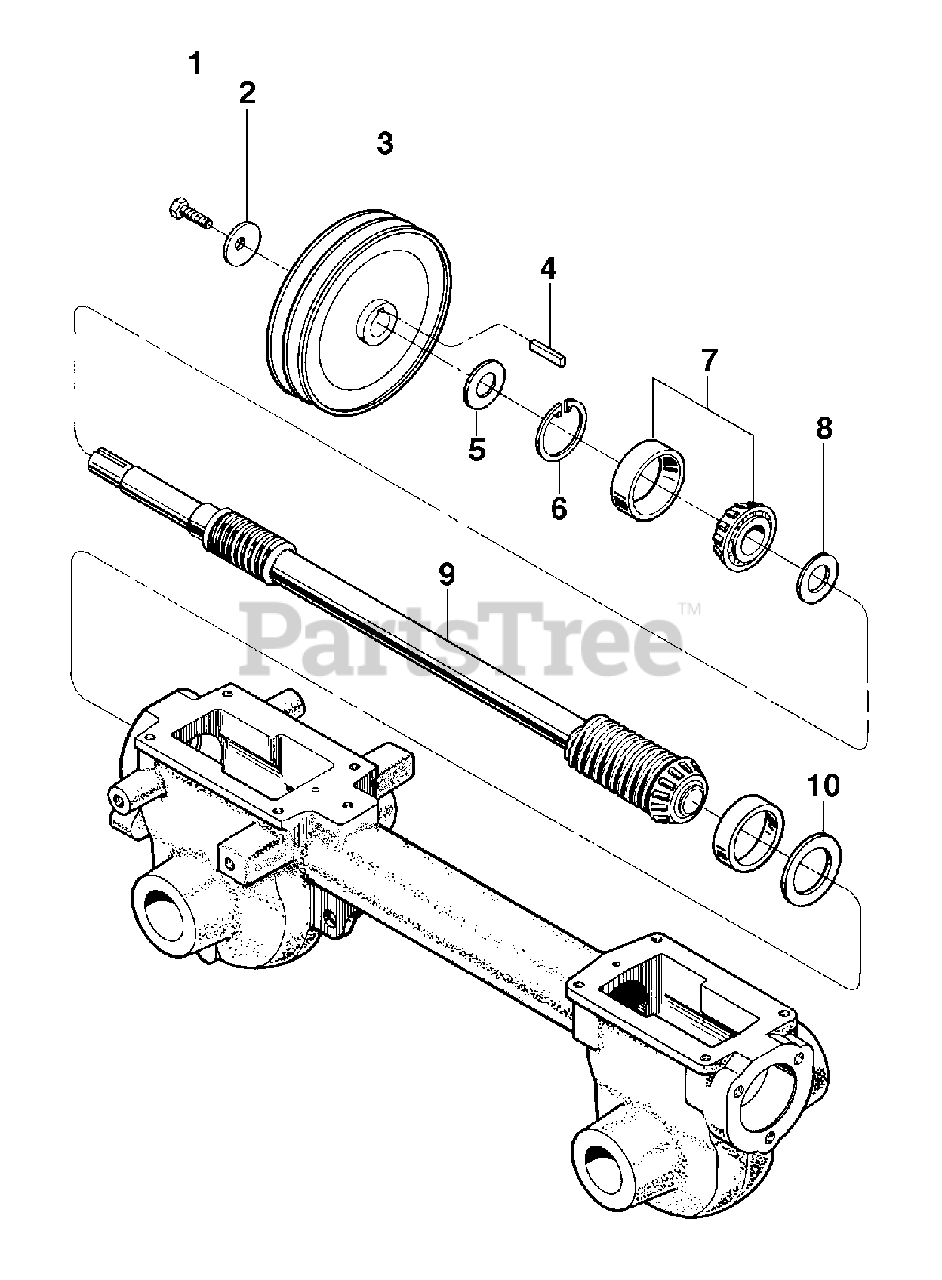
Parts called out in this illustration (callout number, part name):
1	Hex Screw, 5/16-24 x 3/4 Grade 5
1	Hex Screw, 5/16-24 x 1 Grade 5
2	Washer, Belleville
3	Single Groove Pulley, Transmission
3	Double Groove Pulley, Transmission
4	Key - Transmission Pulley, 3/16 x 1
5	Support Washer, Front
6	Snap Ring
7	Bearing, Tapered Roller (with race)
8	Support Washer, Rear
9	Drive Shaft Assembly
10	Shim, Rear Bearing Cap, .010 thick
